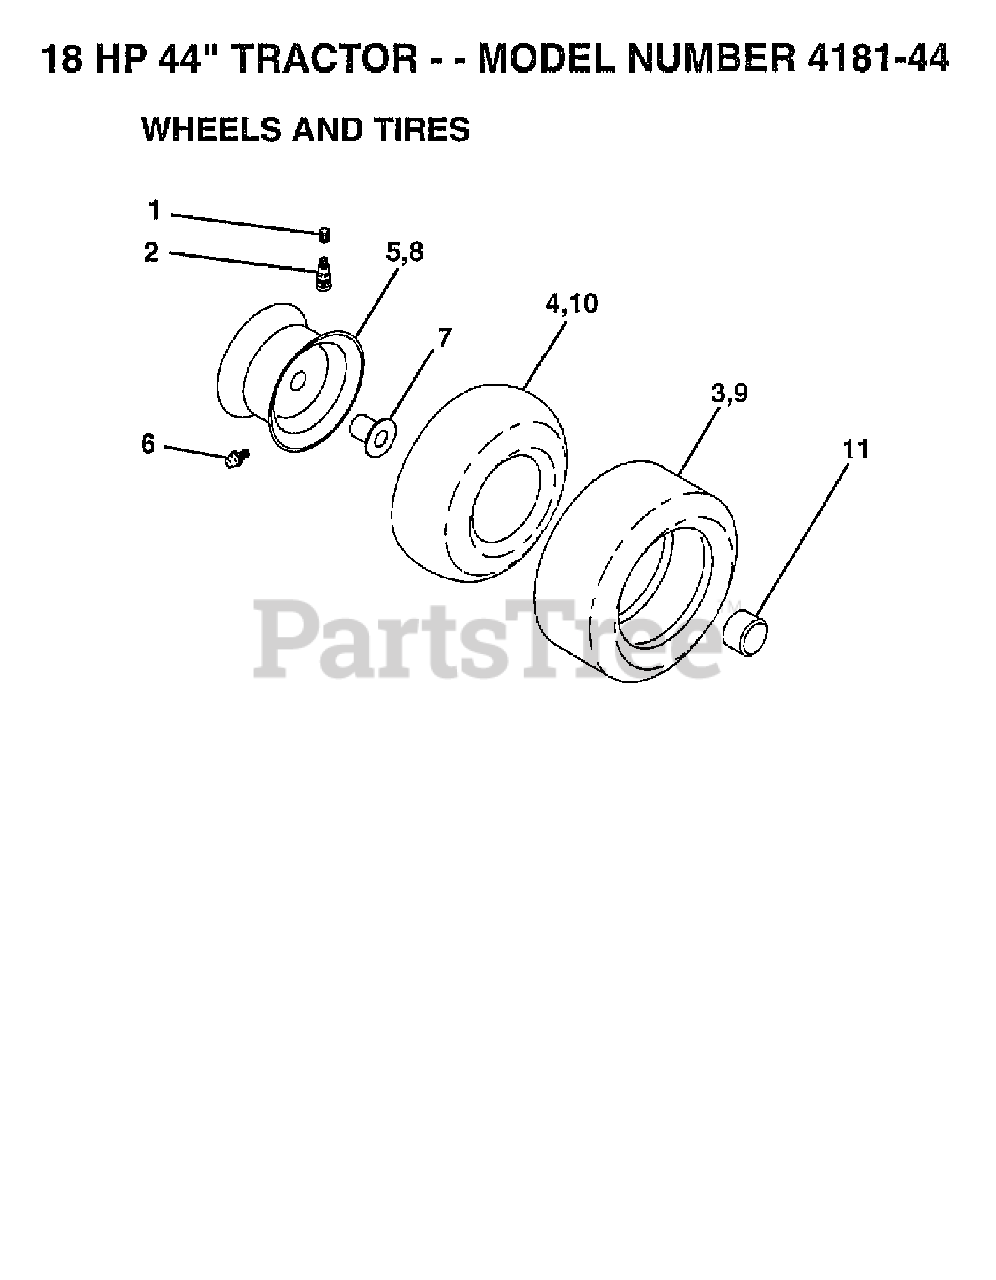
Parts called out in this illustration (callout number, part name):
1	VALVE CAP
2	VALVE STEM LT
3	Tire, .23 X 8.5-12 Turf Saver
4	TUBE.5.3/4.5/6
5	Rim Assembly, 8 X 5 Front Silver
6	FITTING LT
7	BEARING T
9	TIRE HEAVY DUTY
10	TUBE.23"X9.5""X12""
11	CAP.HUB.FRONT.LT.BLACK
